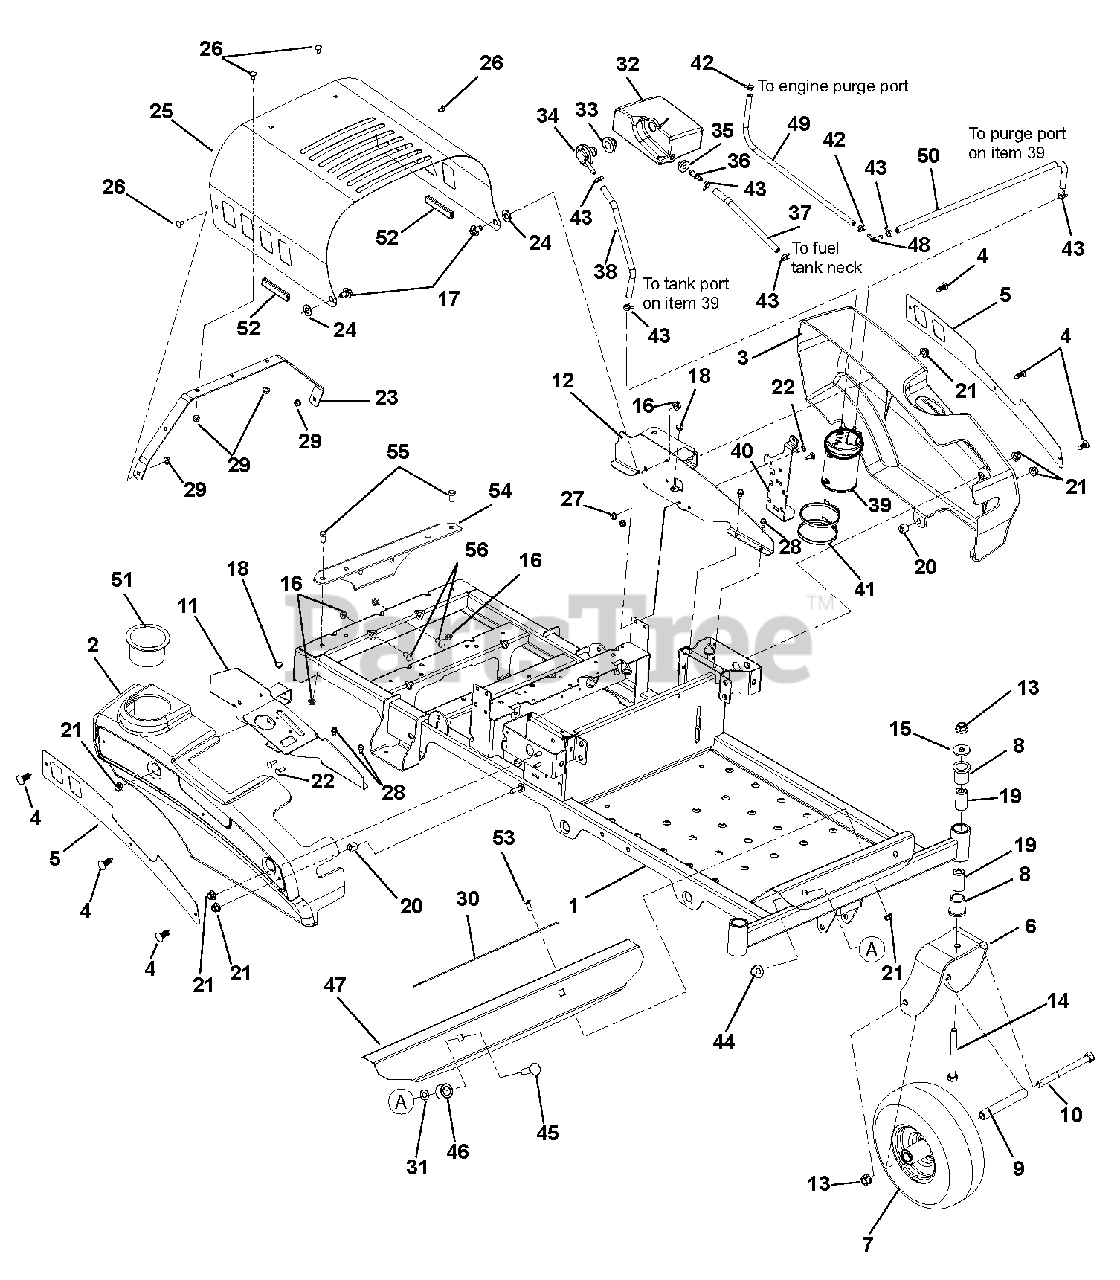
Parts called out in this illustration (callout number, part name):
1	KIT, ZOOM/ZT FRAME W/ DECALS
2	FENDER, RH
3	FENDER, LH
4	RIVET, .25 NYLON PANEL
5	PLATE, FENDER
6	WMT, CASTER FORK
7	TIRE/WHEEL ASSY, 11X4-5
8	BSHG-FLG 1.00X1.25X1.50X1.50
9	SPACER, ROLLED WHEEL
10	@BLT-HEX .50-13X6.50 GR5 YWZC
11	WMT-RH FENDER MOUNT
12	WLDMNT, LH FENDER MOUNT
13	@NUT-LK-TOP-FLG .50-13 YWZC
14	@BLT-HEX .50-13X5.00 GR5 YWZC
15	WSHR-FL-STL.511X1.441X.125 YWZ
16	@NUT-LK-TOP-FLG .38-16 YWZC
17	BOLT-SHLDR .375-16X.150
18	BUMPER GROMMET
19	SPACER, CASTER .50X1.00X1.84
20	BSHG-SLV .391X.688X.52 PM
21	@NUT-LK-NYL-FLG .31-18 YWZC
22	@BLT-RDHDSQNK .25-20X.75 G5YZ
23	BRACE, HOOD
24	WSHR-FL-NYL .518X1.000X.080
25	HOOD, ZOOM
26	@BLT-RDHDSQNK .25-20X.50 G5YZ
27	@NUT-LK-NYL-FLG .25-20 YWZC
28	@SCR-TAP .25-20X.50 HWH TR YWZ
29	@NUT-LK-TOP-FLG .25-20 YWZC
30	GRIP, ADHESIVE (1" X 16" BLK)
31	NUT-PUSH, .50
32	TANK, FUEL EXPANSION
33	GROMMET, REMOTE VENT NITRILE
34	VENT, ROLL-OVER (.25"ID HOSE)
35	BSHG-FLG .375X1.062X.625 NITR
36	FITTING, STRAIGHT FUEL PLASTIC
37	HOSE, .25 LOW-PERM BULK GAS
38	HOSE, .25 LOW-PERM BULK GAS
39	CARBON CANISTER, 300CC
40	BRKT-MOUNT, CANISTER BBZ
41	P-PLASTIC TIE STRAP LARGE
42	CLAMP-HOSE, SPRING .188
43	CLAMP, FUEL LINE
44	@NUT-LK-NYL-FLG .50-13 YWZC
45	@BLT-RDHDSQNK .50-13X1.75 G5YZ
46	TUBE, UPPER CONTROL PIVOT
47	FOOTREST
48	FITTING-3/16X1/4 90DEGREE VAC
49	HOSE, .188 LOW-PERM BULK GAS
50	HOSE, .25 LOW-PERM BULK GAS
51	CUPHOLDER, SNAP-IN 3.75OD
52	EDGING, CLUTCH PADDLE - 2.00"
53	@BLT-RDHDSQNK .31-18X.75 G5YZ
54	PLATE, BBZ HITCH KIT PLATE
55	@BLT-HEX .38-16X.75 GR5 YWZC
56	@BLT-RDHDSQNK .38-16X.75 G5YZ
